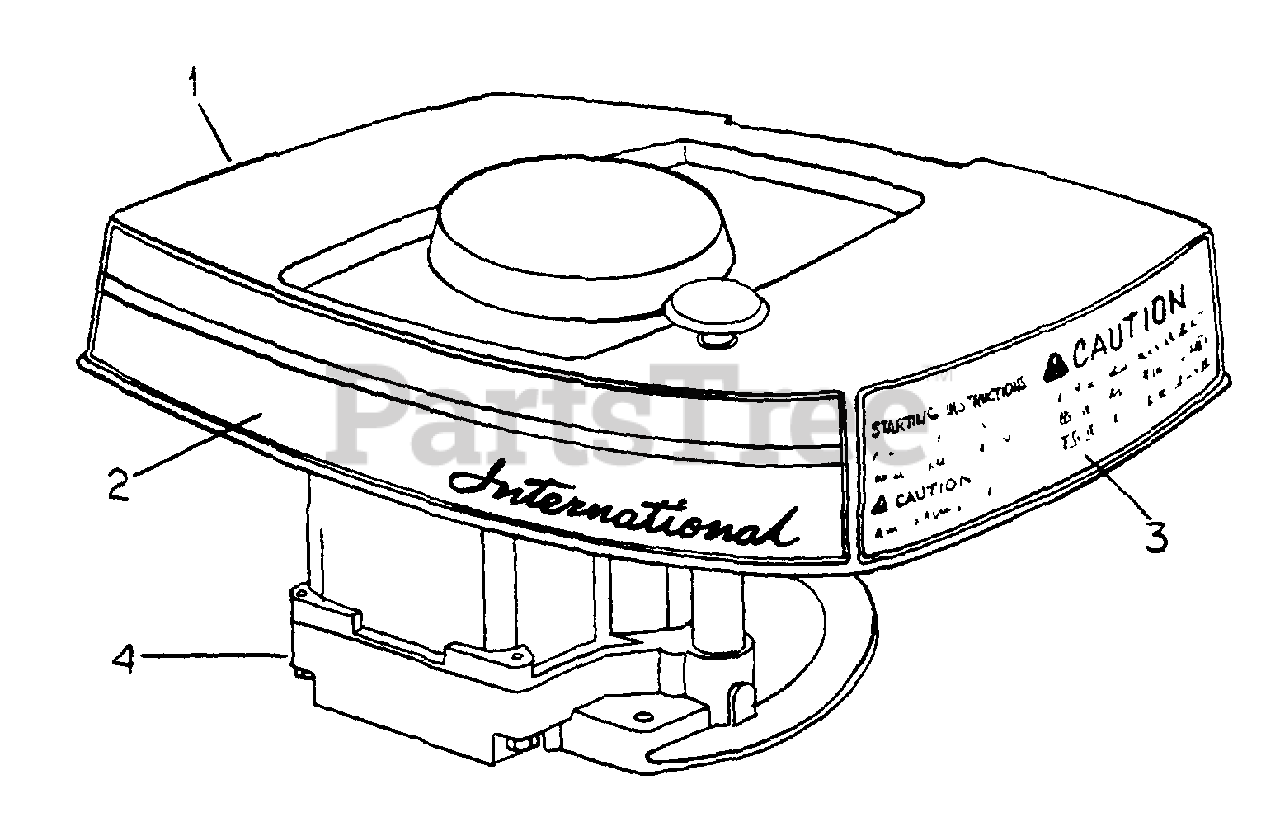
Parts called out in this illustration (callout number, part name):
1	SHROUD, ENGINE
2	PRODUCT GRAPHIC, INTERNATIONAL NAME TRADEMARK
3	PRODUCT GRAPHIC, CAUTION AND STARTING INSTRUCTIONS
4	ENGINE ASSY, 3 HORSEPOWER
